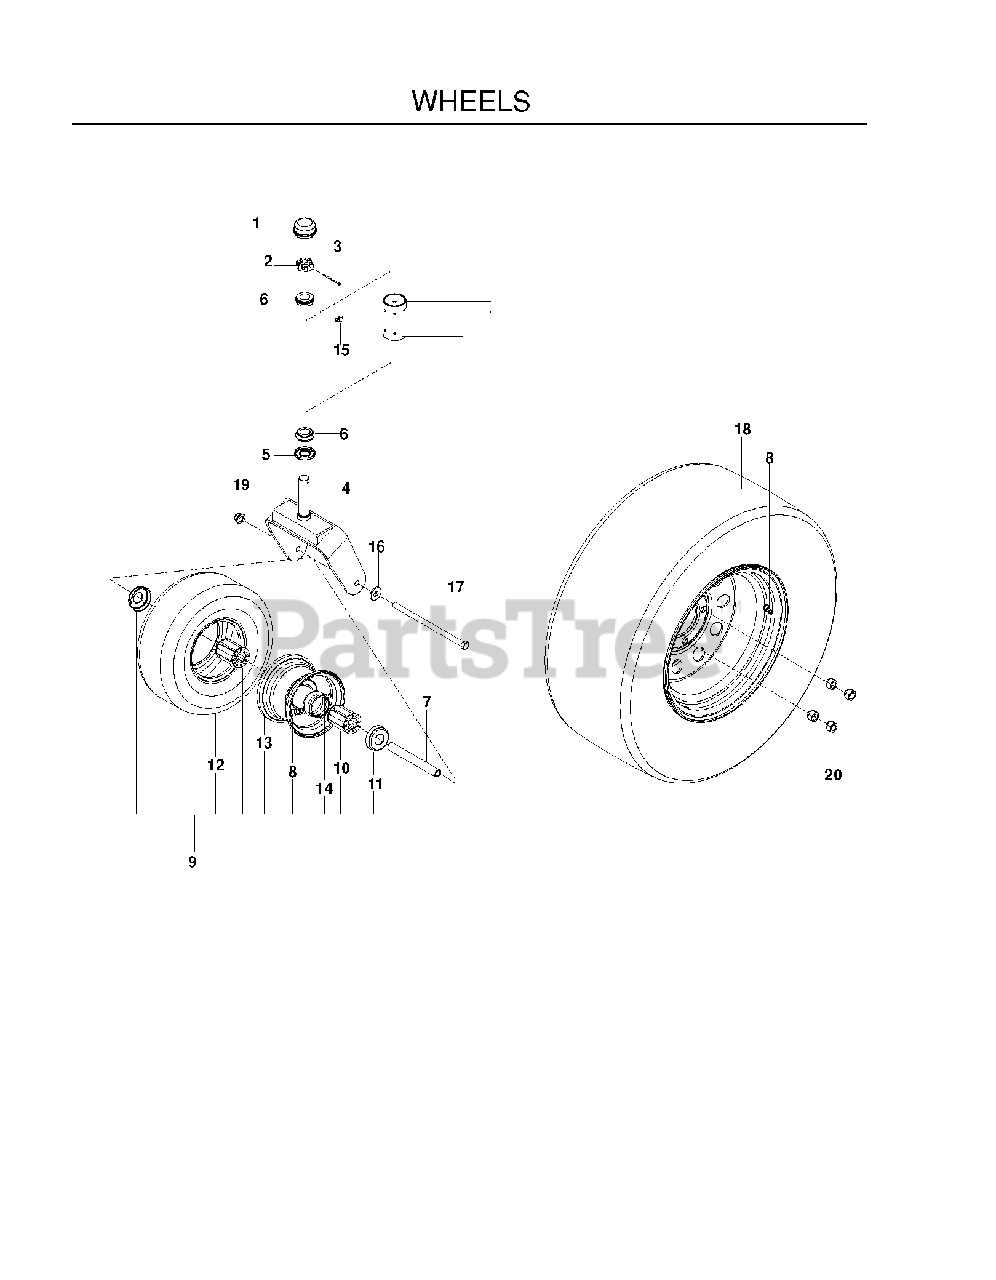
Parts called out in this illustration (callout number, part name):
1	GREASE CAP
2	NUT 1"C HEX SLOTTED
3	COTTER PIN 1/8 X 2
4	CASTER YOKE ORANGE
6	TAPERED ROLLER BRG
7	SPACER, CASTER
8	VALVE STEM TR-412
9	TIRE.ASSEM.13X5-6.SMOOTH.SILVE
10	ROLLER BEARING
11	BEARING RETAINER
12	TIRE - FRONT
13	RIM
14	NUT 10-24 NYLOC
16	WASH USS FLAT 1/2
17	SCREW 1/2C X 7 1/2 HEX CAP
18	TIRE/WHEEL.ASM.22X9.5-10
19	NUT, 1/2-13 HEX FLG NYLOC ZD
20	LUG NUT 1/2F
